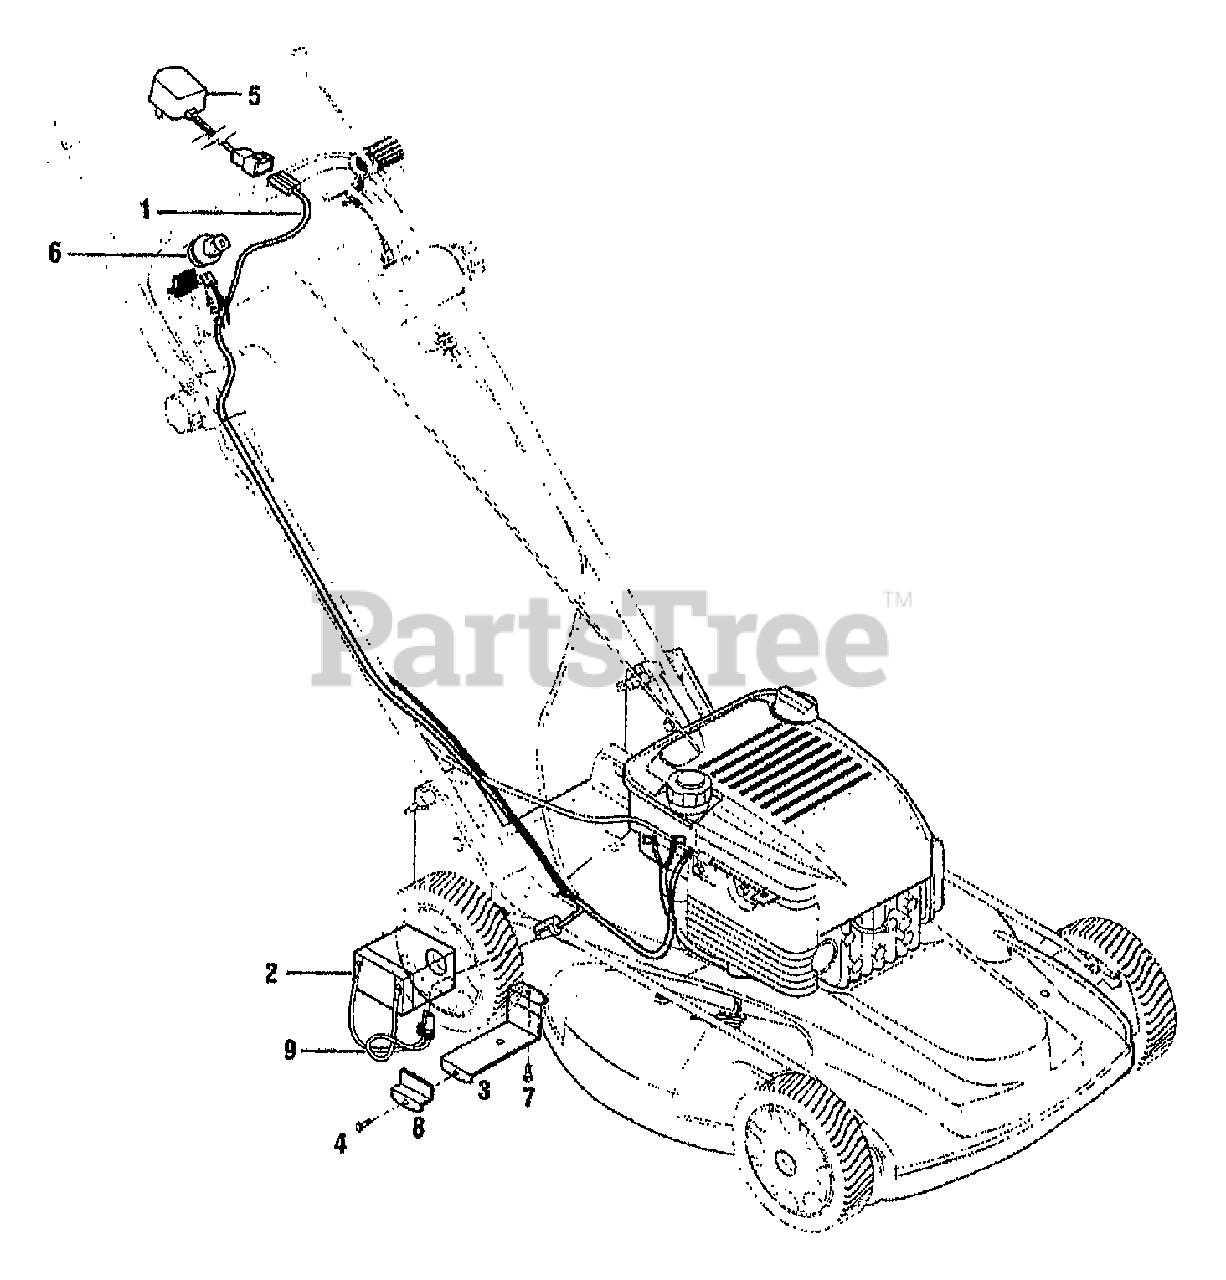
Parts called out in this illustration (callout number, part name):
1	HARNESS-WIRE
2	BATTERY ES2.9-12
3	BRKT-BATTERY PAINTED
4	SCR-FLANGE 1/4-20X3/4 GR5
5	CHARGER-BATTERY
6	IGNITION SWITCH COMPONENTS
7	SCR-HWH 1/4-20 X .5 STH
8	BRKT-BATTERY NGMM
9	CONNECTOR-BATTERY
